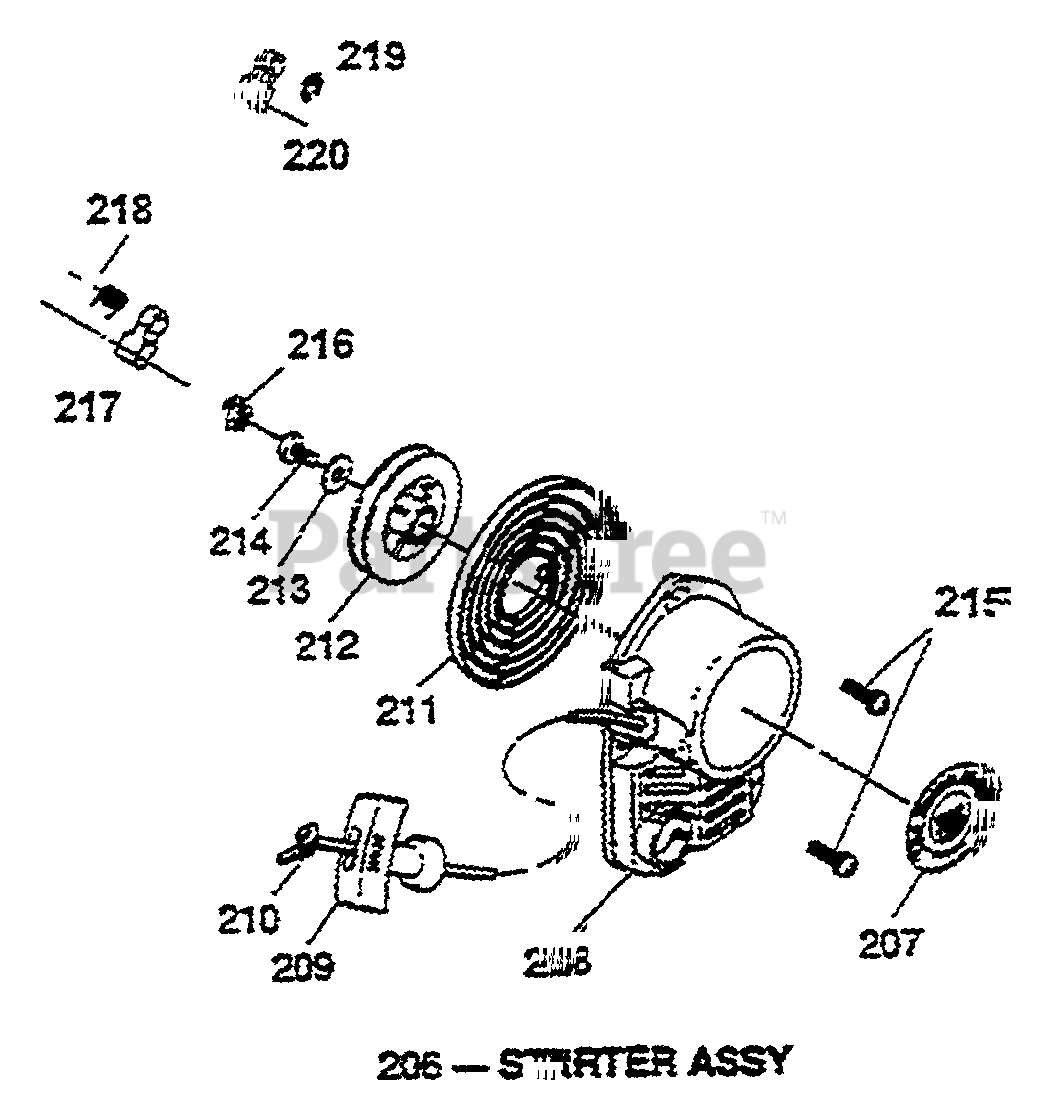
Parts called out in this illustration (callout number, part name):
206	STARTER ASSY
207	LABEL, NAME
208	CASE, STARTER
209	KNOB, STARTER
210	ROPE, STARTER
211	SPRING, SPIRAL
215	BOLT AND WASHER
219	SNAP RING
